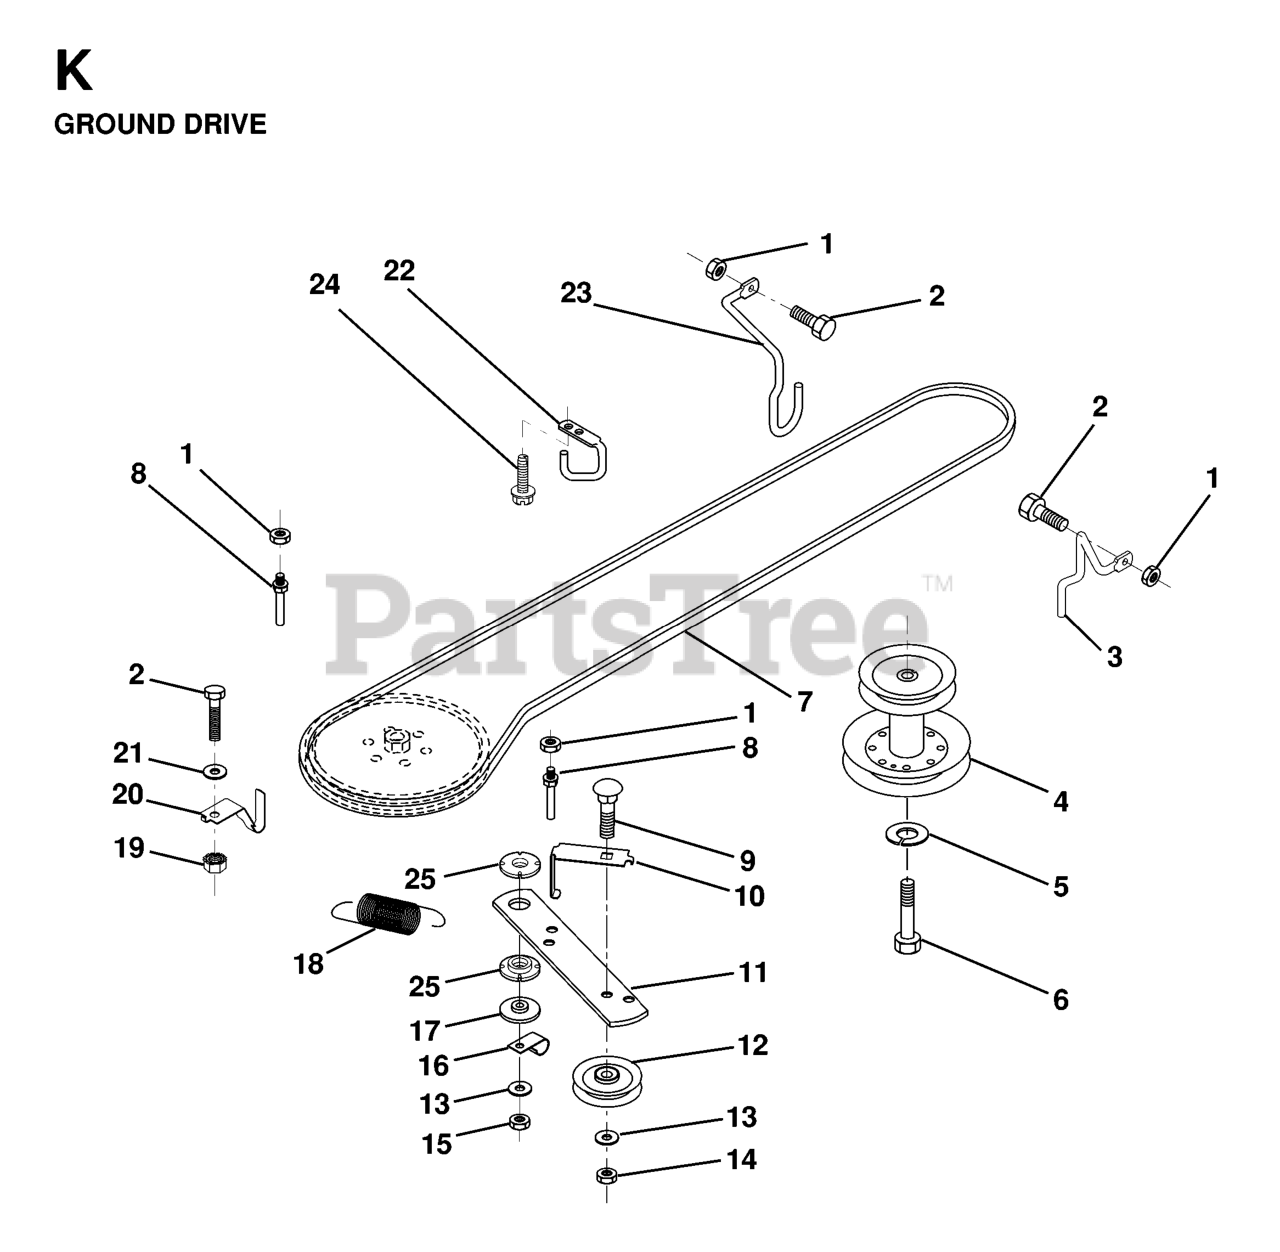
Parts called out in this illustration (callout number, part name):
1	LOCKNUT
2	BOLT
3	KEEPER/MOWER DRIVE RH
4	PULLEY.ENGINE.36/38 LR
5	LOCKWASHER
6	Bolt, Hex Hd. 7/16-20 UNF Grade 5
8	KEEPER,DRIVE BELT
9	Bolt, Carriage 3/8-16 UNC x 1-1/2
10	KEEPER.BELT.GROUND.DRIVE.IDLER
11	ARM, GROUND DRIVE CLUTCH
12	PULLEY.IDLER.FLAT
13	WASHER
14	LOCKNUT
16	CLIP,INSULATOR
17	SPACER, RETAINER
18	SPRING.EXTENSION
19	NUT
20	KEEPER-T/A GROUND DRIVE BELT
21	Washer 11/32 x 5/8 x 16 Ga SD
22	KEEPER,FRA DR BEL
23	KEEPER-MOWER DRIVE LH
24	SCREW
25	BUSHING NYLON COLLERED
